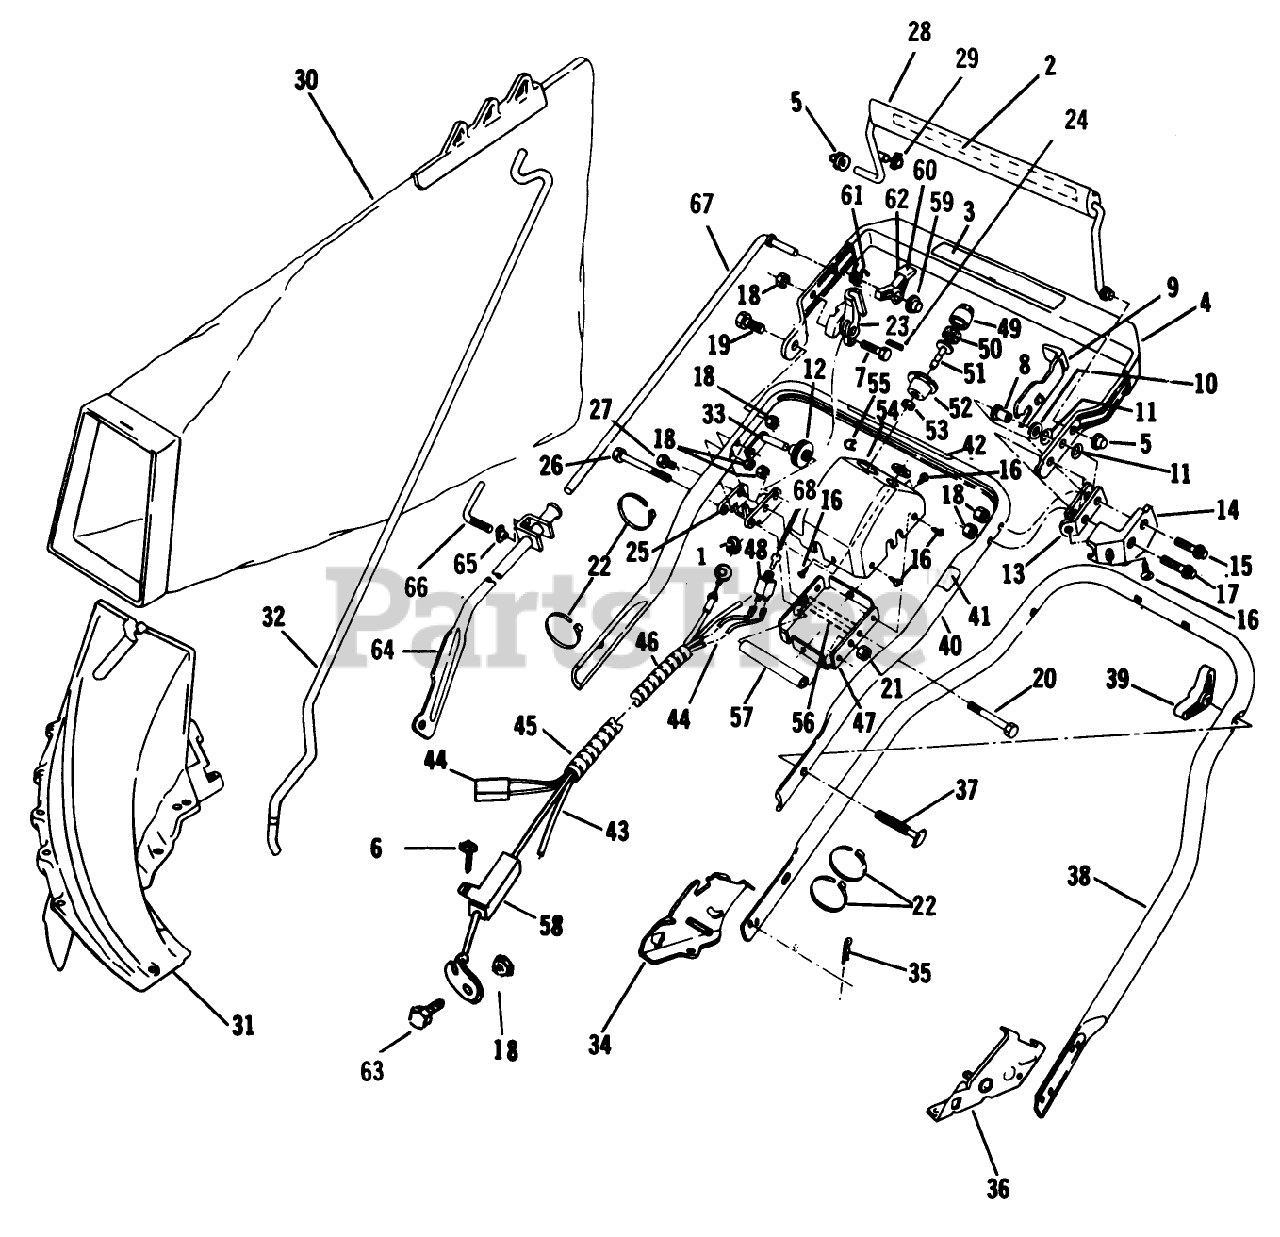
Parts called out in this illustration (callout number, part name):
1	RET. RING
6	SCREW-HH
7	Bolt-Hex
8	SPACER
10	WASHER M
13	DOWN STOP
14	LOCKOUT GUARD
15	BOLT SHOU
16	SCREW F
17	SCREW
18	LOCKNUT E
19	BOLT
23	CAM (12)
26	BOLT-CONSOLE
29	NUT ACORN
30	89802 LB WHOLE GOODS
32	ROD GRASSBAG
34	BRACKET ASM - HANDLE, SP, RH
35	HAIR PIN
36	BRACKET ASM - HANDLE, SP, LH
37	BOLT QUALITY
39	NUT-WING
48	SWITCH AY
50	FILTER S
53	LOCKNUT S
56	SPACER
58	CONTROL CABLE
